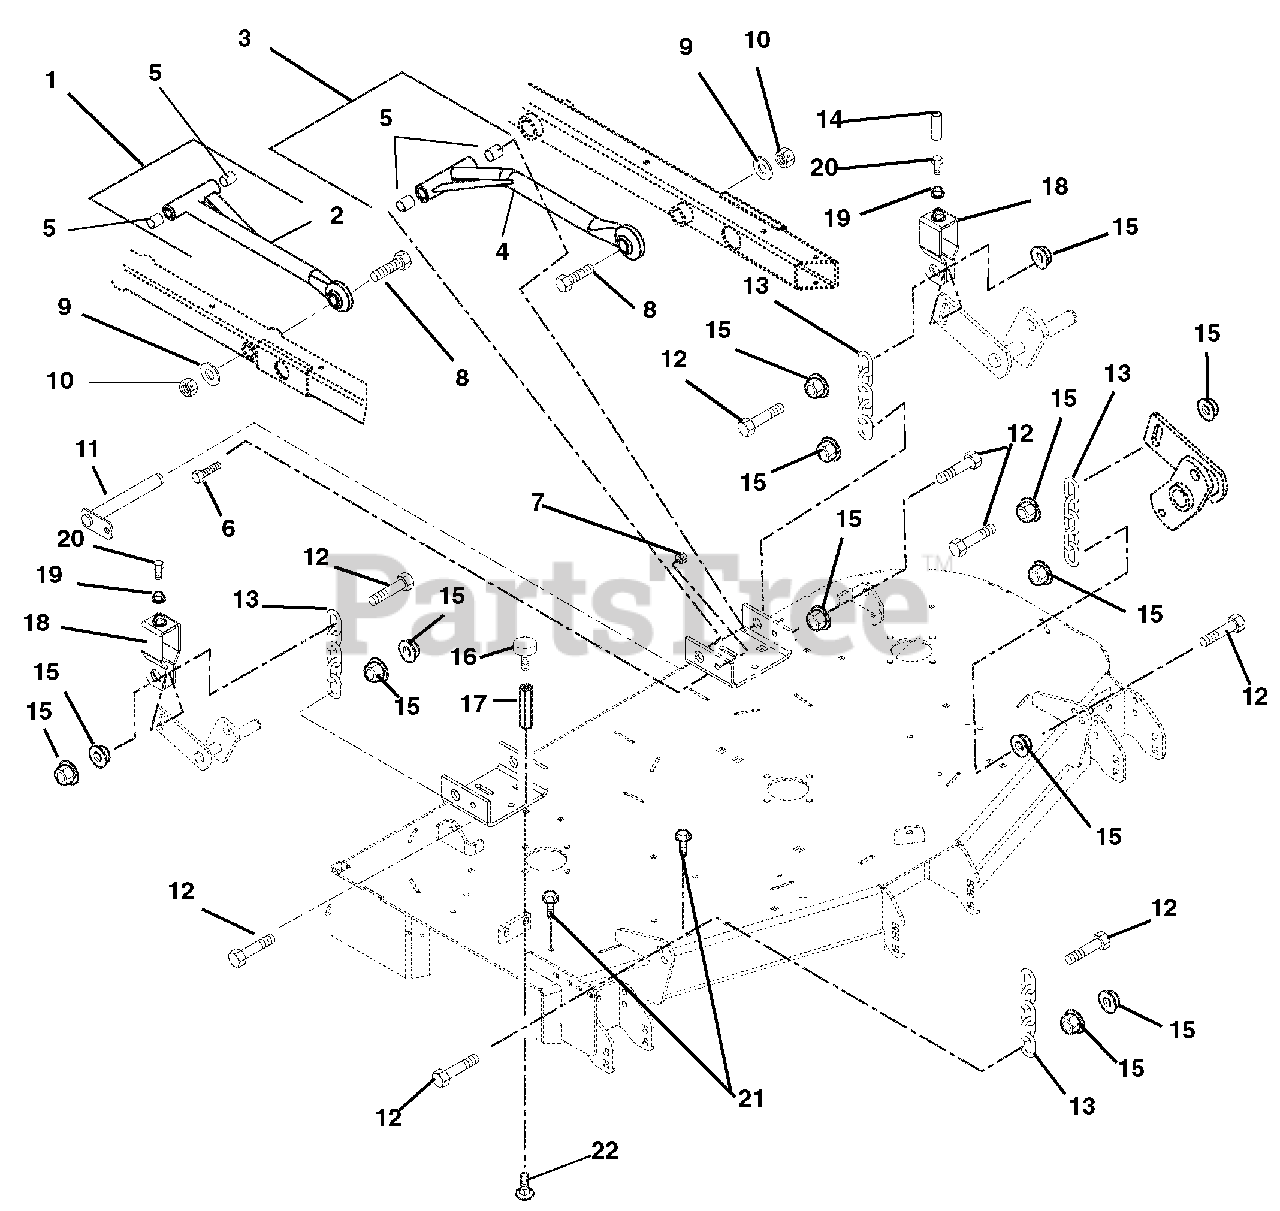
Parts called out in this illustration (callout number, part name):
1	Assembly, Mower Mounting Arm (Contains Items 2, 5)
2	Weldment, Mower Mounting Arm
3	Assembly, Mower Mounting Arm Left Hand (Contains Items 4,5)
4	Weldment, Mower Mount Arm
5	Bearing .75 x .875 x 1.00
6	Bolt-Hex .38-16 x .75 Grade 5
7	Nut, .38-16 Nyloc Flange
8	Bolt, Hex .875 x 5.50 Grade 5
9	Washer, Flat-Steel .875 x 1.500 x .1196
10	Nut, Locking-Center .875-9
11	Weldment, Mower Mounting Pin
12	Bolt, Hex M12-1.75 x 50 Grade 5
13	Chain, Link
14	Cap, Vinyl .50 ID x 1.50LG x .055
15	Nut, Spin Lock-Flange M12-1.75
16	Bumper, Rubber
17	Nut, Coupling .31-18 x 3.00
18	Bracket, Deck Leveling
19	Nut, Jam .312-18
20	Bolt, Full Thread Hex .312-18 x 2.00
21	Screw, Tapping Hex Washer Head Thread .38-16 x .50
22	Bolt, Round Head Square Neck .31-18 x .75
